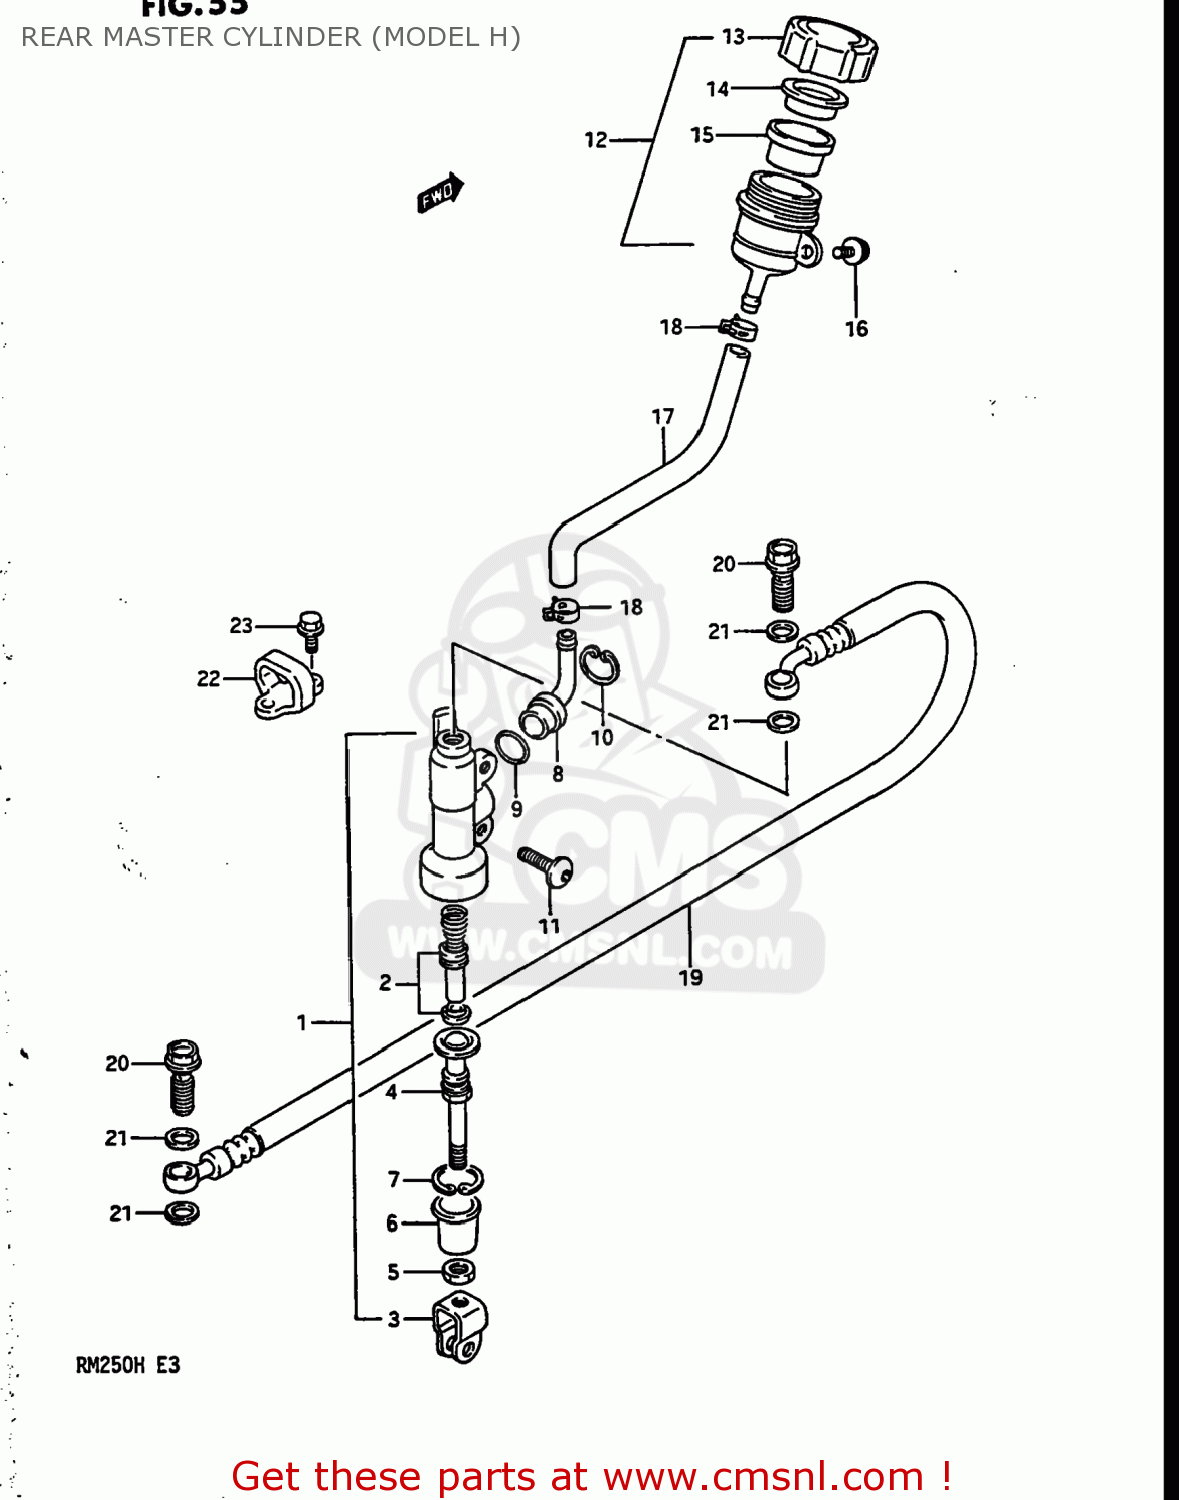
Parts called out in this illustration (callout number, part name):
1	CYLINDER ASSEMBLY,REAR MASTER
2	PISTON/CUP SET
3	YOKE
4	ROD,PUSH
5	NUT
6	BOOT
7	CIRCLIP
8	CONNECTOR
9	O RING
10	CIRCLIP
11	BOLT(6X18)
12	TANK ASSEMBLY,RESERVOIR
13	CAP
14	PLATE
15	DIAPHRAGM
16	BOLT
17	HOSE,RESERVOIR TANK
18	CLAMP,RESERVOIR HOSE
19	HOSE COMP,REAR BRAKE
20	BOLT UNION
21	WASHER(10X15X1.5)
22	GUIDE,REAR BRAKE HOSE
23	SCREW
